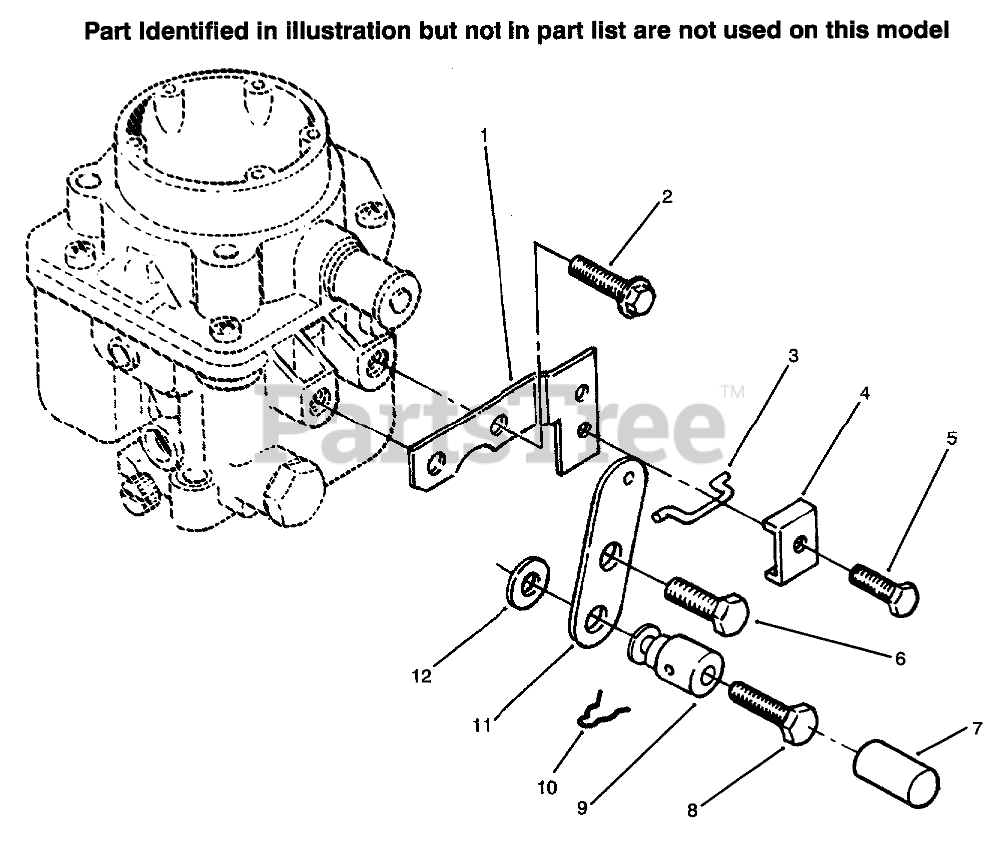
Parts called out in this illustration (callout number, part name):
1	BRACKET
2	SCREW-HWH
3	LINK-CHOKE
5	SCREW-TAPPING
6	MACHINE SCREW
8	SCREW
9	SWIVEL
10	PIN-COTTER
11	Lever-Choke
12	Washer
